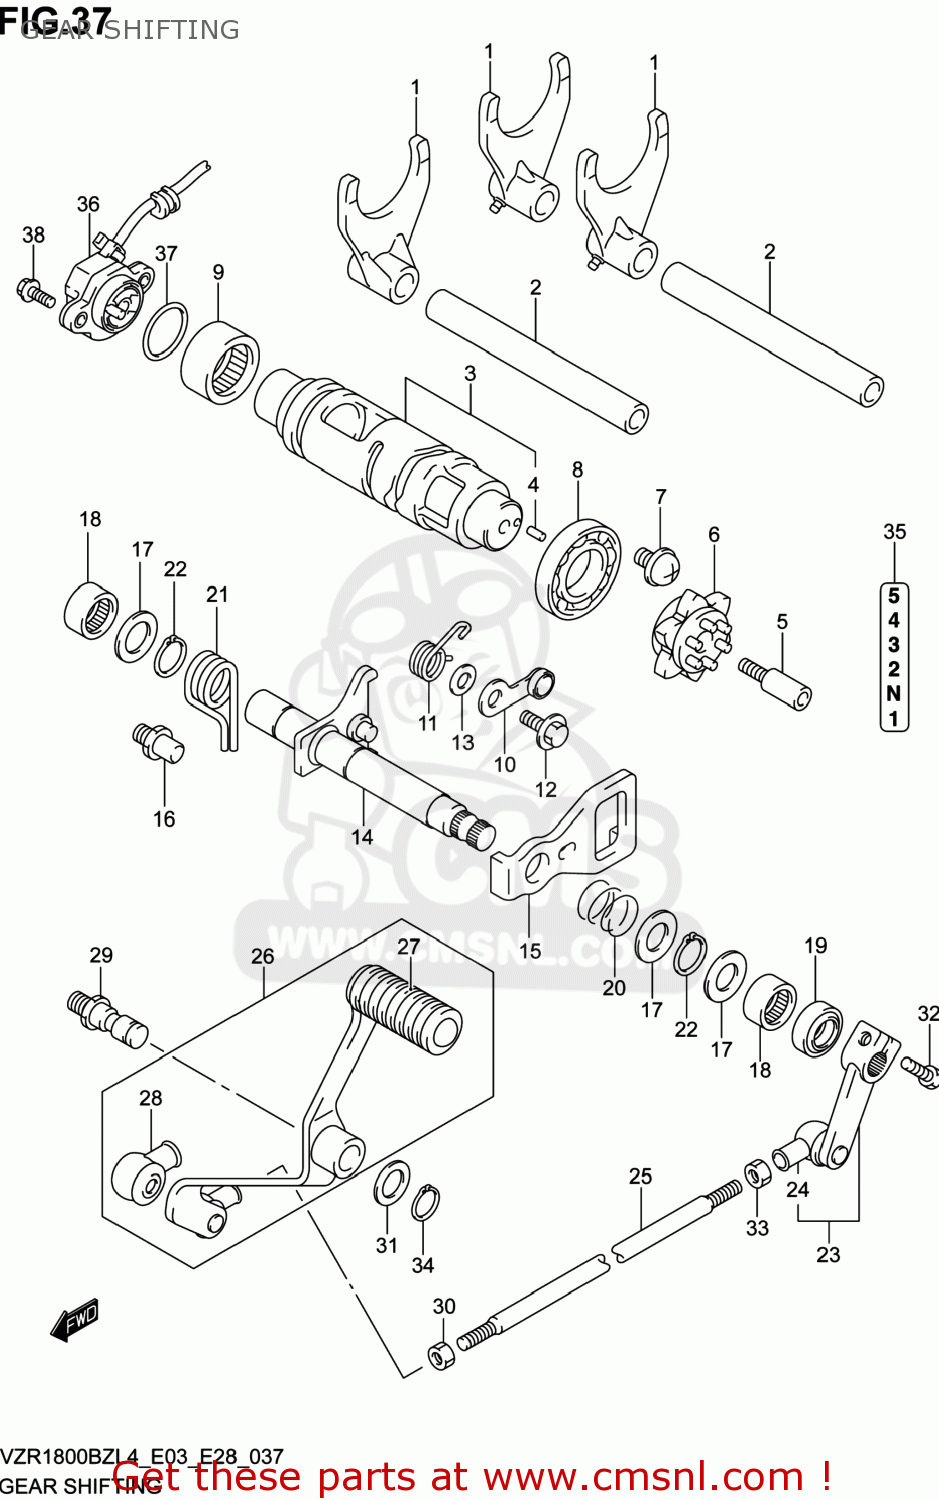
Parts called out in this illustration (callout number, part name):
1	FORK,GEAR SHIFT NO.1
2	SHAFT,GEAR SHIFT FORK
3	CAM,GEAR SHIFT
4	PIN
5	BOLT,GEAR SHIFT CAM PLATE
6	PLATE,GEAR SHIFT CAM
7	SCREW(6X12)
8	BEARING(25X47X8)
9	BEARING(25X32X12)
10	STOPPER,SHIFT CAM
11	SPRING,GEAR SHIFT CAM STOPPER
12	BOLT(6X14.3)
13	WASHER
14	SHAFT,GEAR SHIFT
15	PLATE,GEAR SHIFT CAM DRIVE
16	STOPPER,GEAR SHIFT ARM
17	SHIM(14X22X1)
18	BEARING(14X20X12)
19	SEAL,OIL(14X22X7.3)
20	SPRING
21	SPRING
22	CIRCLIP
23	ARM,GEAR SHIFT LINK
24	COVER,DUST
25	ROD,GEAR SHIFT LINK
26	LEVER ASSY,GEAR SHIFT
27	RUBBER,GEAR SHIFT PEDAL
28	COVER,DUST
29	SHAFT,GEAR SHIFT LEVER
30	NUT
31	WASHER(12.5X20X1)
32	BOLT
33	NUT
34	CIRCLIP
35	LABEL,GEAR SHIFT
36	SENSOR ASSY,GEAR POSITION
37	O RING(D:2.4,ID:26.2)
38	BOLT(5X16)
